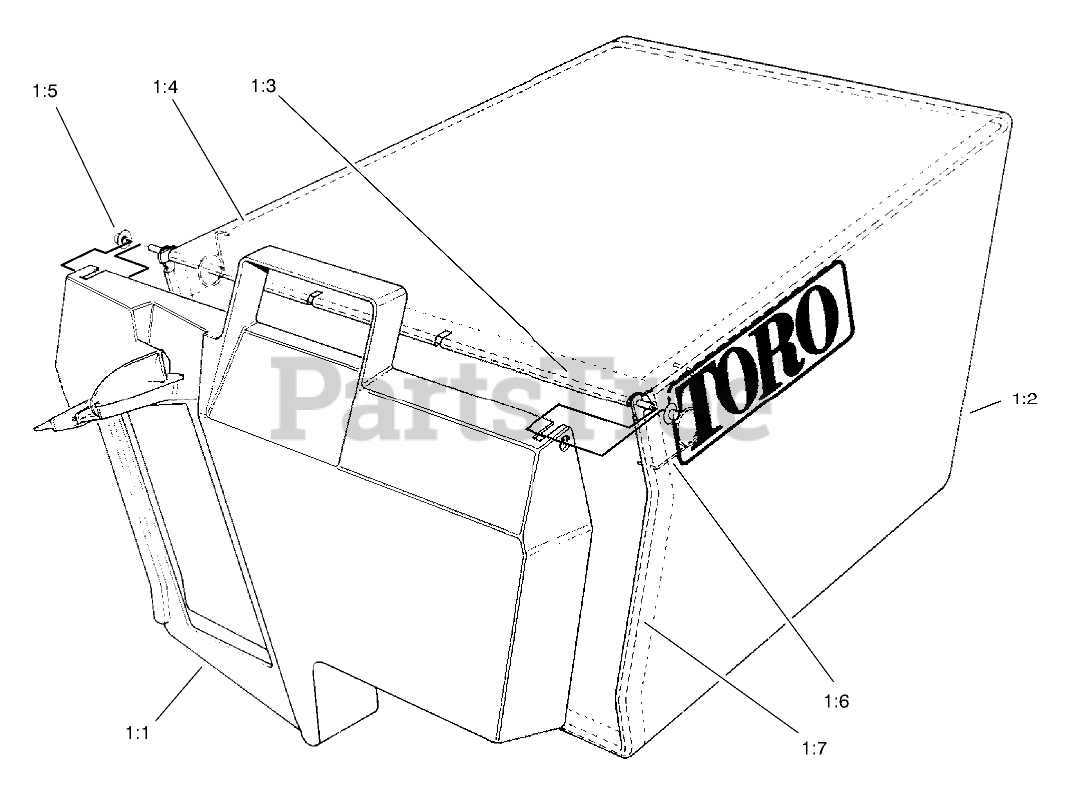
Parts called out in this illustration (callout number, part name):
1:1	DOOR-BAG
1:2	Bag-Grass
1:3	HINGE-DOOR, BAG
1:4	FRAME-BAG, UPPER
1:5	NUT-PUSH
1:6	SPRING
1:7	FRAME-BAG
